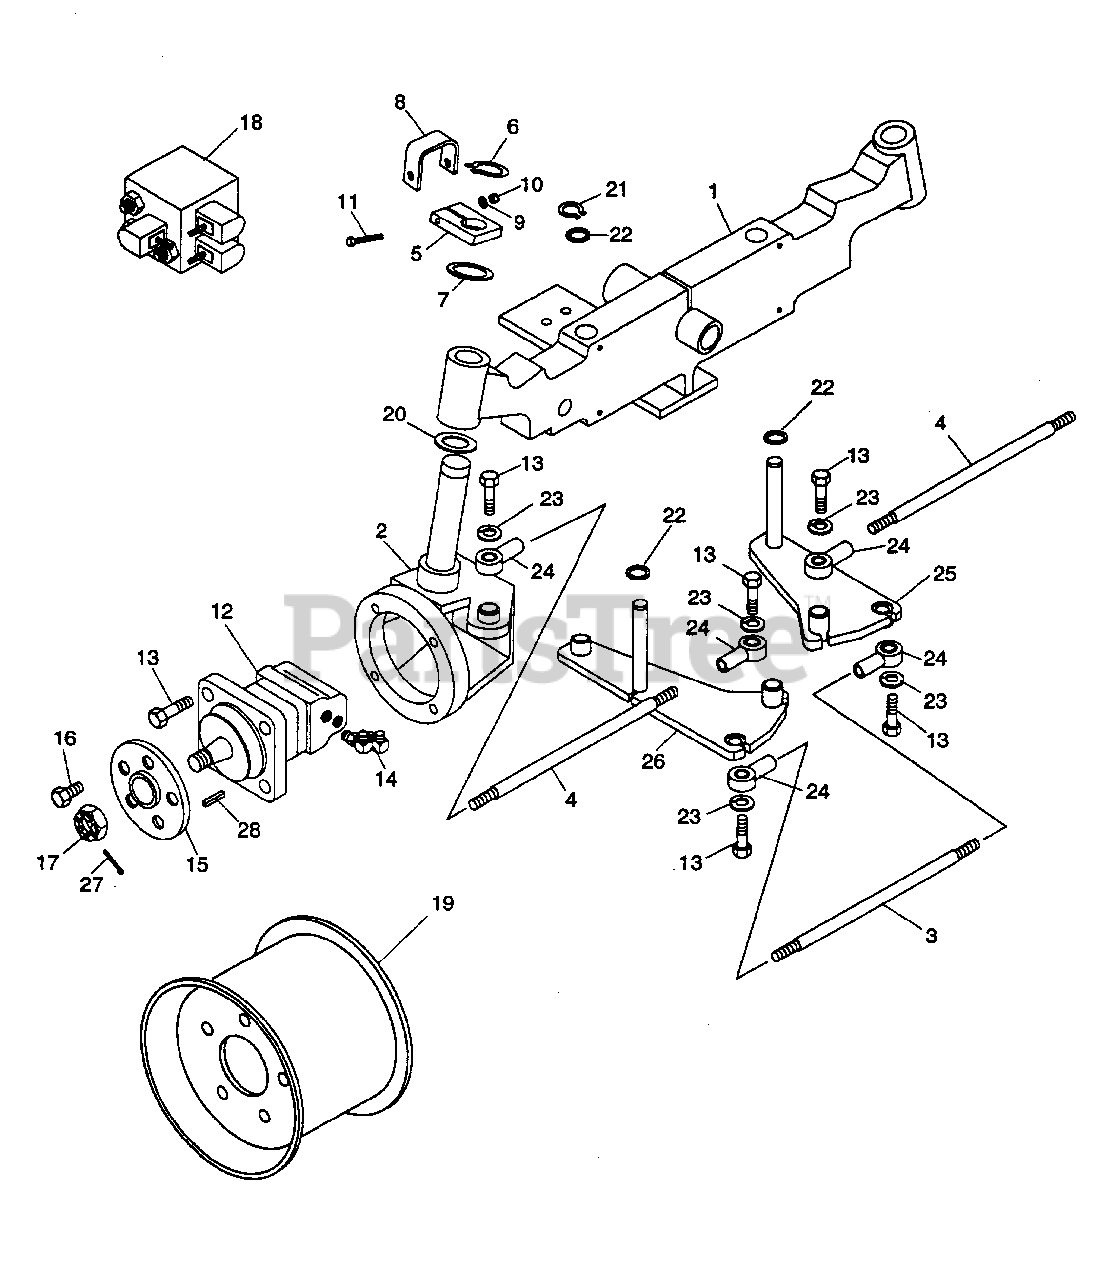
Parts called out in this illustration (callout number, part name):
1	Axle, Weldment
2	Spindle Wldmt, R.H.
2	Spindle Wldmt, L.H.
5	Clamp Tube Support
6	Rg-Rtng-Ext 1.250x.050
7	Wshr-Thrst 1.27x2.25x18 Ga
8	Bracket Hose Loop
9	Wshr-Fl-Stl .250x.484x.047
10	Nut-Lk-Nyl .250-20 Pl
11	Blt-Hex .25-20x2.75
12	Wheel Motor
13	Blt-Hex .50-13x1.50 Pl Gr 5
14	Fitting, Hydrostat Adapter
16	Wheel Bolt Dexter 7-40
17	Nut-Sl 1.0-14
18	Slope Control Valve
20	Wshr-Thrst 1.27x2.25x.156
21	Rg-Rtng-Ext .750x.078
22	Wshr-Thrst 1.00x1.56x.125
23	Wshr-Lock .50 Reg.
24	Rod End, L.H. 1/2-20
24	Rod End, R.H. 1/2-20
25	Steering Arm Weldment, R.H.
26	Steering Arm Weldment, L.H.
27	Pin-Cotr .12x2.0
28	Key-Sq .313x1.00
NS	Assembly, Hydraulic Hose
NS	Switch, Slope Control
NS	Bracket, Switch
NS	Clamp, Cushioned Steel
NS	Nut, Hex Special
NS	Blt-Hex .38-16x1.00 Pl
NS	Wire Assembly
NS	Power Switch, Four Wheel Drive
NS	Repair Kit, Eaton 2000 Motor
